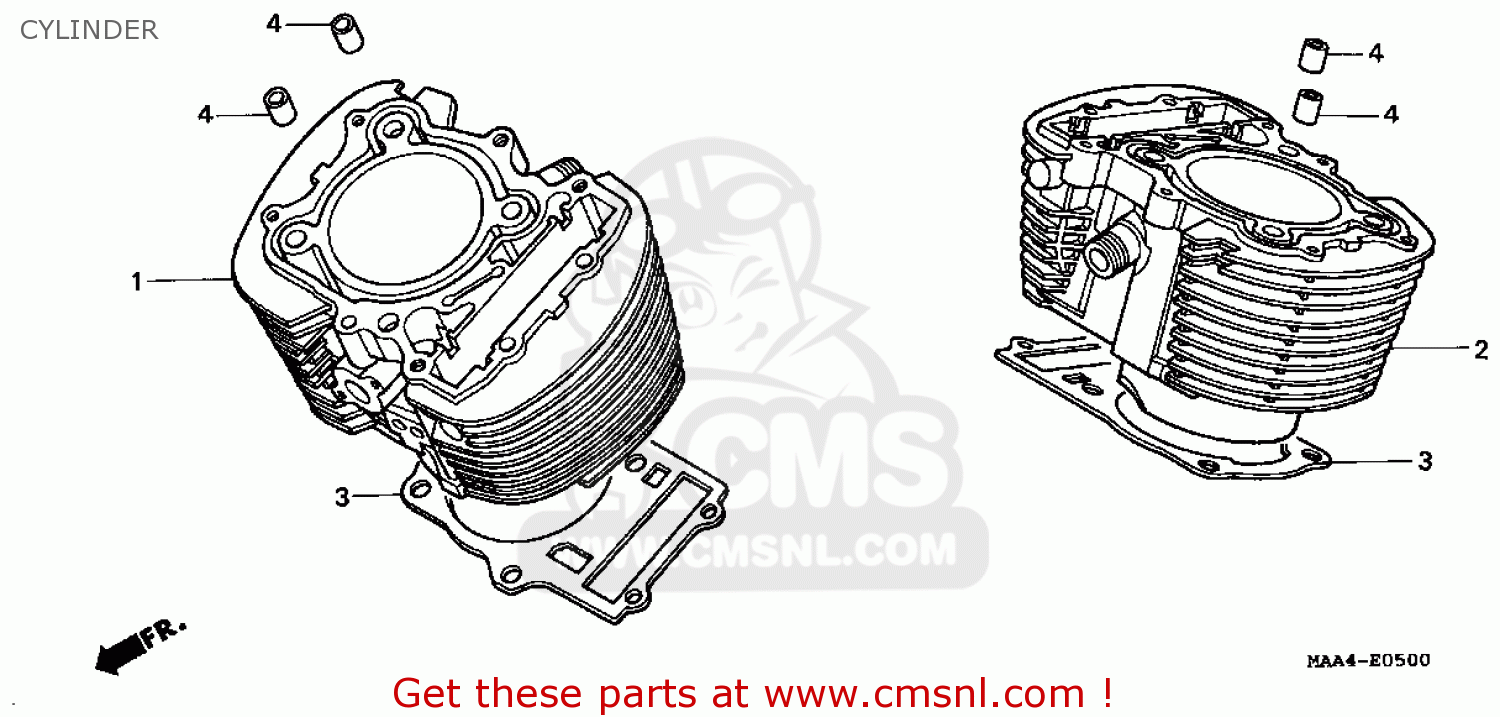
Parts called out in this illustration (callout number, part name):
1	CYLINDER COMP,FR
2	CYLINDER COMP,RR
3	GASKET,CYLINDER (NAS)
4	DOWEL,PIN,14X20
